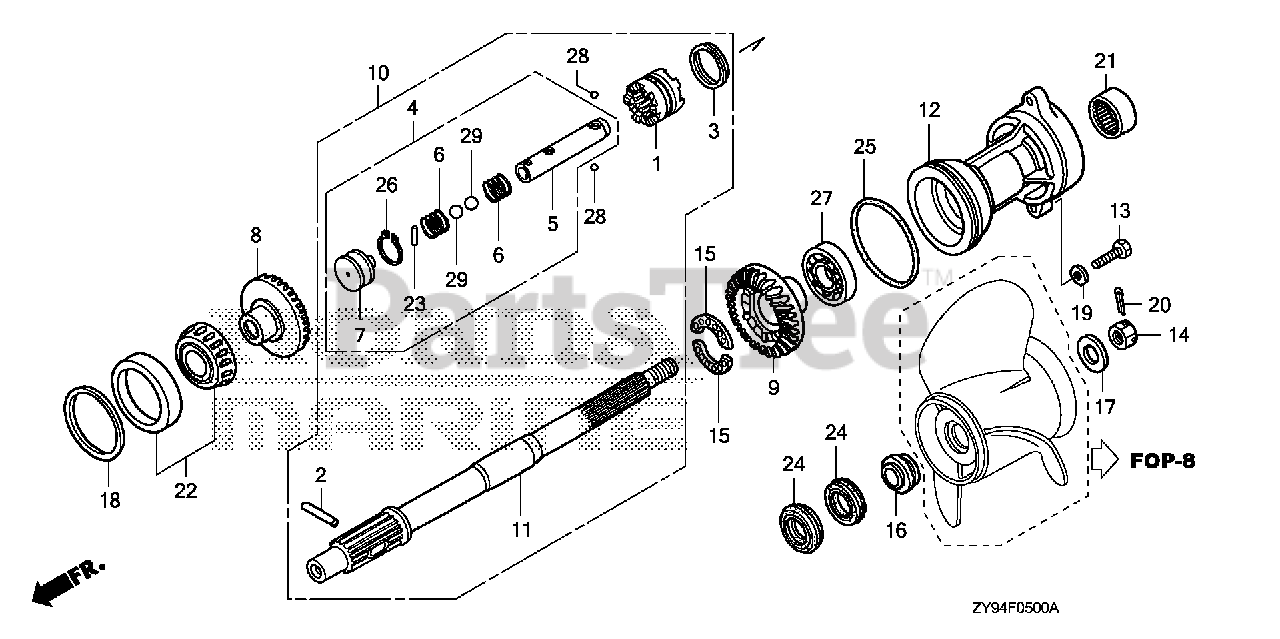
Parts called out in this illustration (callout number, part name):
1	SHIFTER, CLUTCH
2	PIN, SHIFTER (8X47)
3	RING, CROSS PIN
4	SLIDER, SHIFT
5	SLIDER, SHIFT
6	SPRING, SHIFT
7	PLATE, SHIFT
8	GEAR, FR. BEVEL
9	GEAR, RR. BEVEL
10	SHAFT ASSY., PROPELLER
11	SHAFT, PROPELLER
12	HOLDER, PROPELLER SHAFT *NH282MU* (OYSTER SILVER METALLIC-U)
13	BOLT, HEX. (10X40)
14	NUT, CASTLE (18MM)
15	BEARING, BALL (28X38X3)
16	WASHER, PROPELLER THRUST
17	WASHER, PLAIN (18.5MM)
18	SHIM A, BEVEL (0.10) (FR.)
18	SHIM B, BEVEL (0.15) (FR.)
18	SHIM C, BEVEL (0.30) (FR.)
18	SHIM D, BEVEL (0.50) (FR.)
19	WASHER, PLAIN (10MM)
20	PIN, SPLIT (4.0)
21	BEARING, NEEDLE (30X37X26)
22	BEARING, TAPERED ROLLER (50X82X21.5)
23	ROLLER (3X12.8)
24	SEAL, WATER (30X45X7)
25	O-RING (94X4.1)
26	CIRCLIP (OUTER) (14MM)
27	BEARING, RADIAL BALL (6208)
28	BALL, STEEL (#7) (7/32)
29	BALL, STEEL (#11) (11/32)
